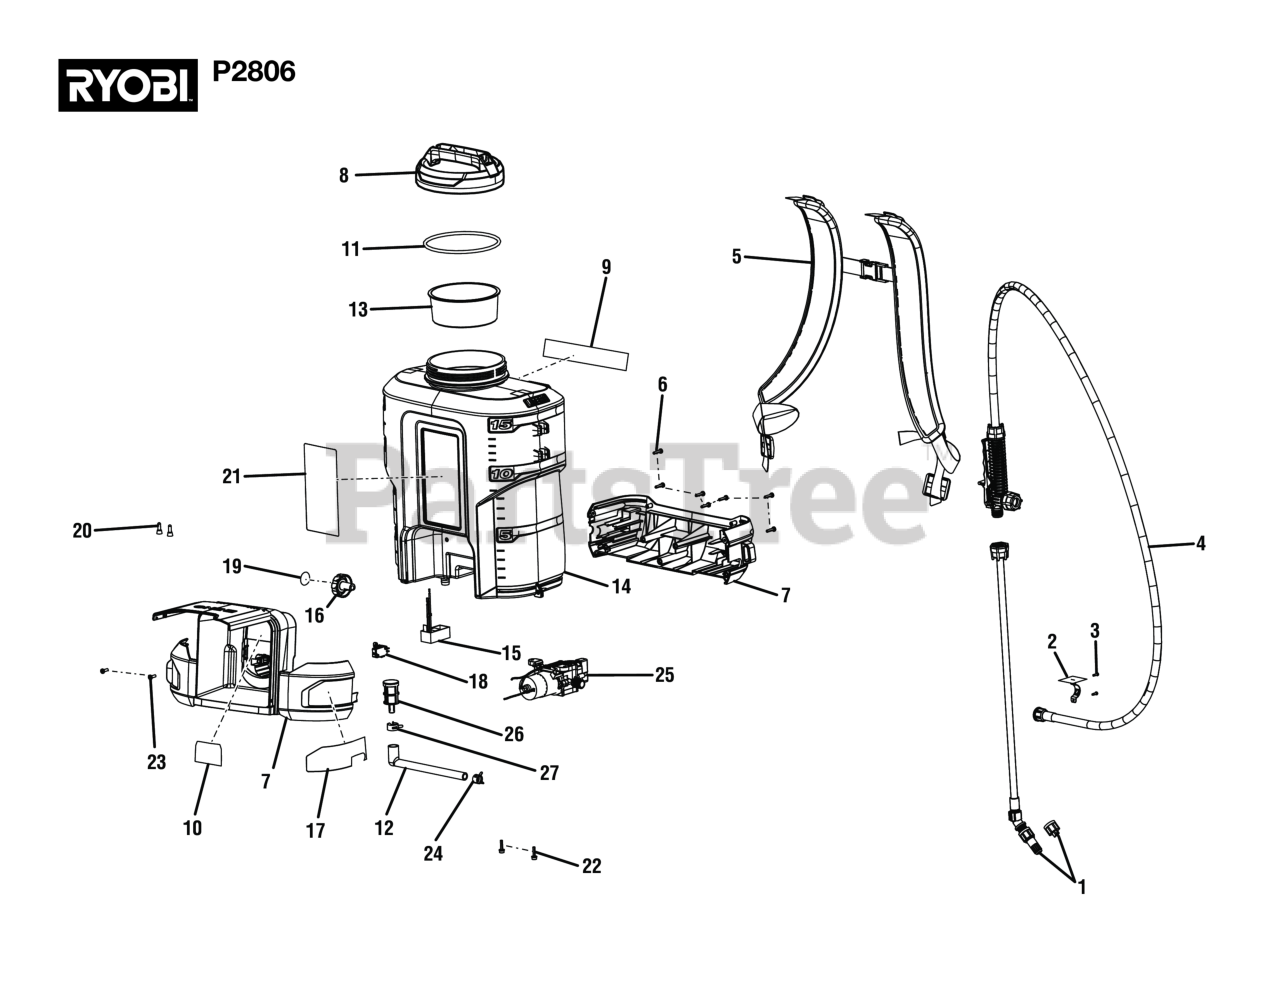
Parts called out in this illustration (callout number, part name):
1	Nozzle and Wand Assembly
3	Screw (M3 x 10 mm, T10 Torx Hd.)
4	Handle and Hose Assembly
6	Screw (M4 x 22 mm Pan Hd.)
7	Housing Assembly (Inc. Key Nos. 10 & 17)
8	Tank Lid Assembly (Inc. Key No. 11)
9	Icon Warning Label
10	Data Label
11	Rubber Gasket
13	Inlet Filter
14	Tank Assembly (Inc. Key Nos. 9 & 21)
15	Flow Rate Control Assembly
16	Adjustable Switch Knob Assembly (Inc. Key No. 19)
17	Warning Label (FR/SP)
18	Micro Switch
19	On\Off Label
20	Wire Connector (Closed End)
21	Logo Label
22	Screw w/Washer (M4 x 19 mm, T20 Torx Pan Hd. S.T.)
23	Screw (M4 x 12 mm)
24	Hose Clamp on Pump
25	Motor and Pump Assembly
26	Filter Assembly
27	Hose Clamp on Tank
